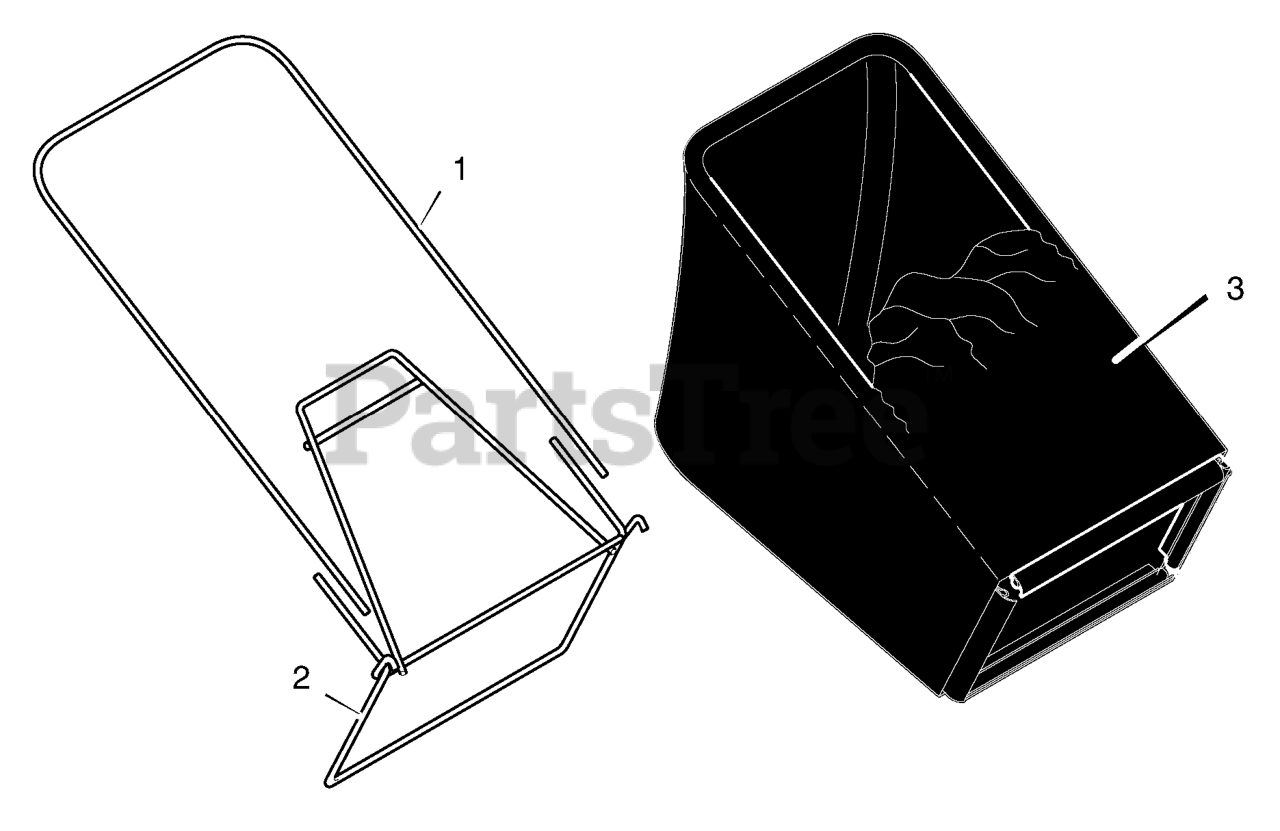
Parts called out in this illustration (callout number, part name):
1	Tube, Bag
2	Frame Assembly
3	Bag, Cloth ï Black
